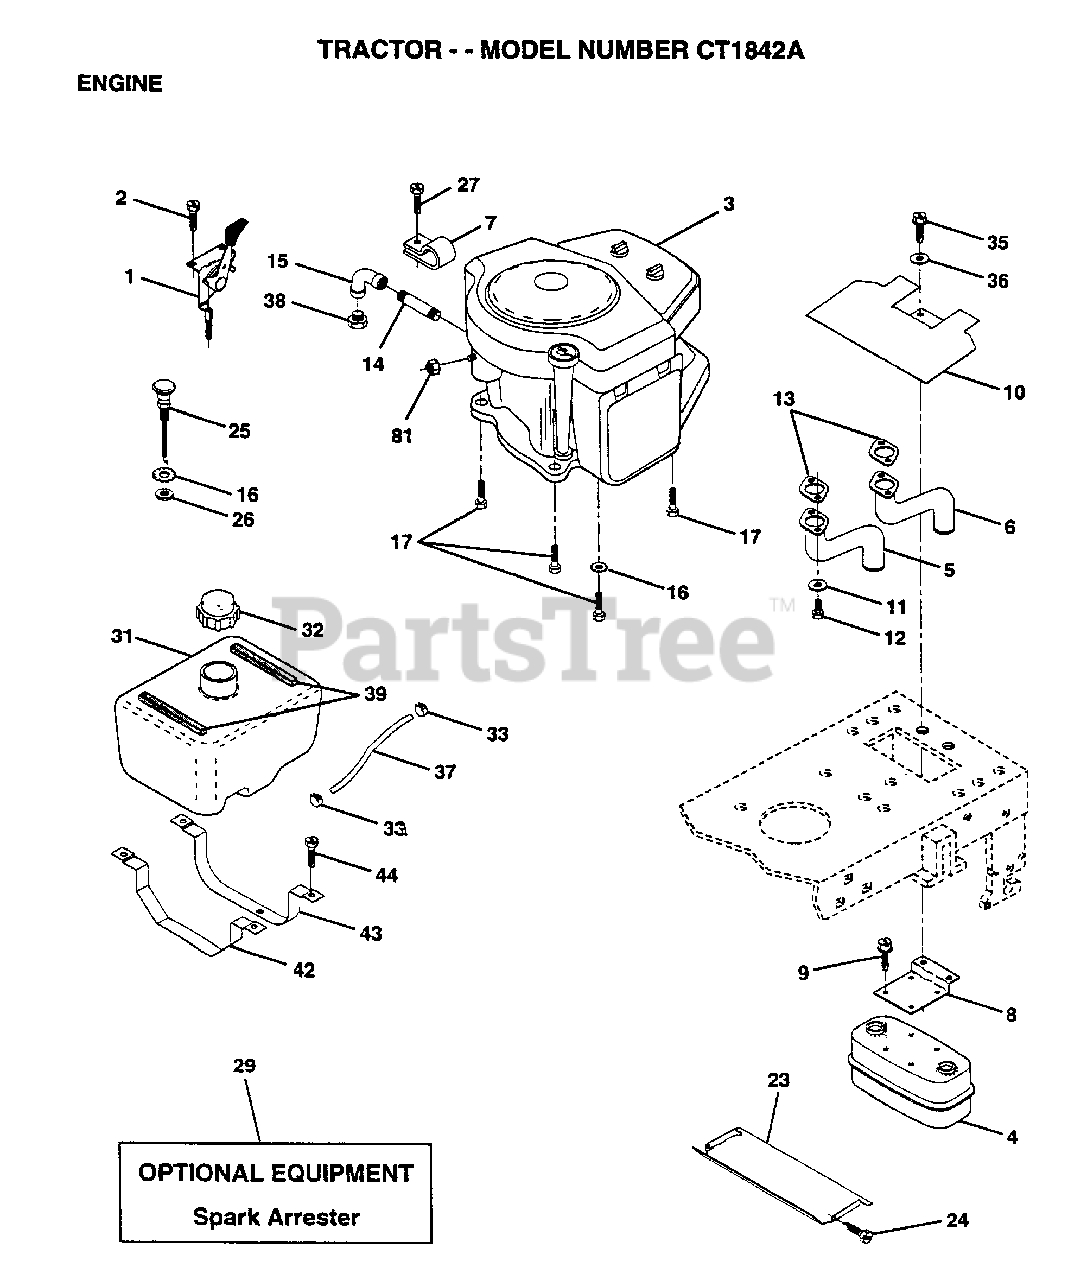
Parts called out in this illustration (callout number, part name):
2	SCREW LT
5	EXHAUST.B&S.18.LH
6	EXHAUST.B&S.18.RH
7	CLAMP.TUBE.DBL.EN
8	BRACKET MUFFLER
9	SCREW ST
10	SHIELD.HEAT.
11	LOCKWASHER
14	PIPE NIPPLE LT
15	ELBOW
16	LOCKWASHER
17	SCREW LT
23	HEAT SHIELD
24	SCREW
25	CONTROL.CHOKE.37
27	SCREW.10-24X1/2
31	TANK FUEL 1.9 NAT
32	CAP ASM FUEL
33	HOSE CLAMP
35	SCREW
36	WASHER
37	FUEL LINE T
39	"STRIP,FORM"
42	STRAP TANK FUEL
43	STRAP TANK FRONT
44	SCREW
81	NUT
